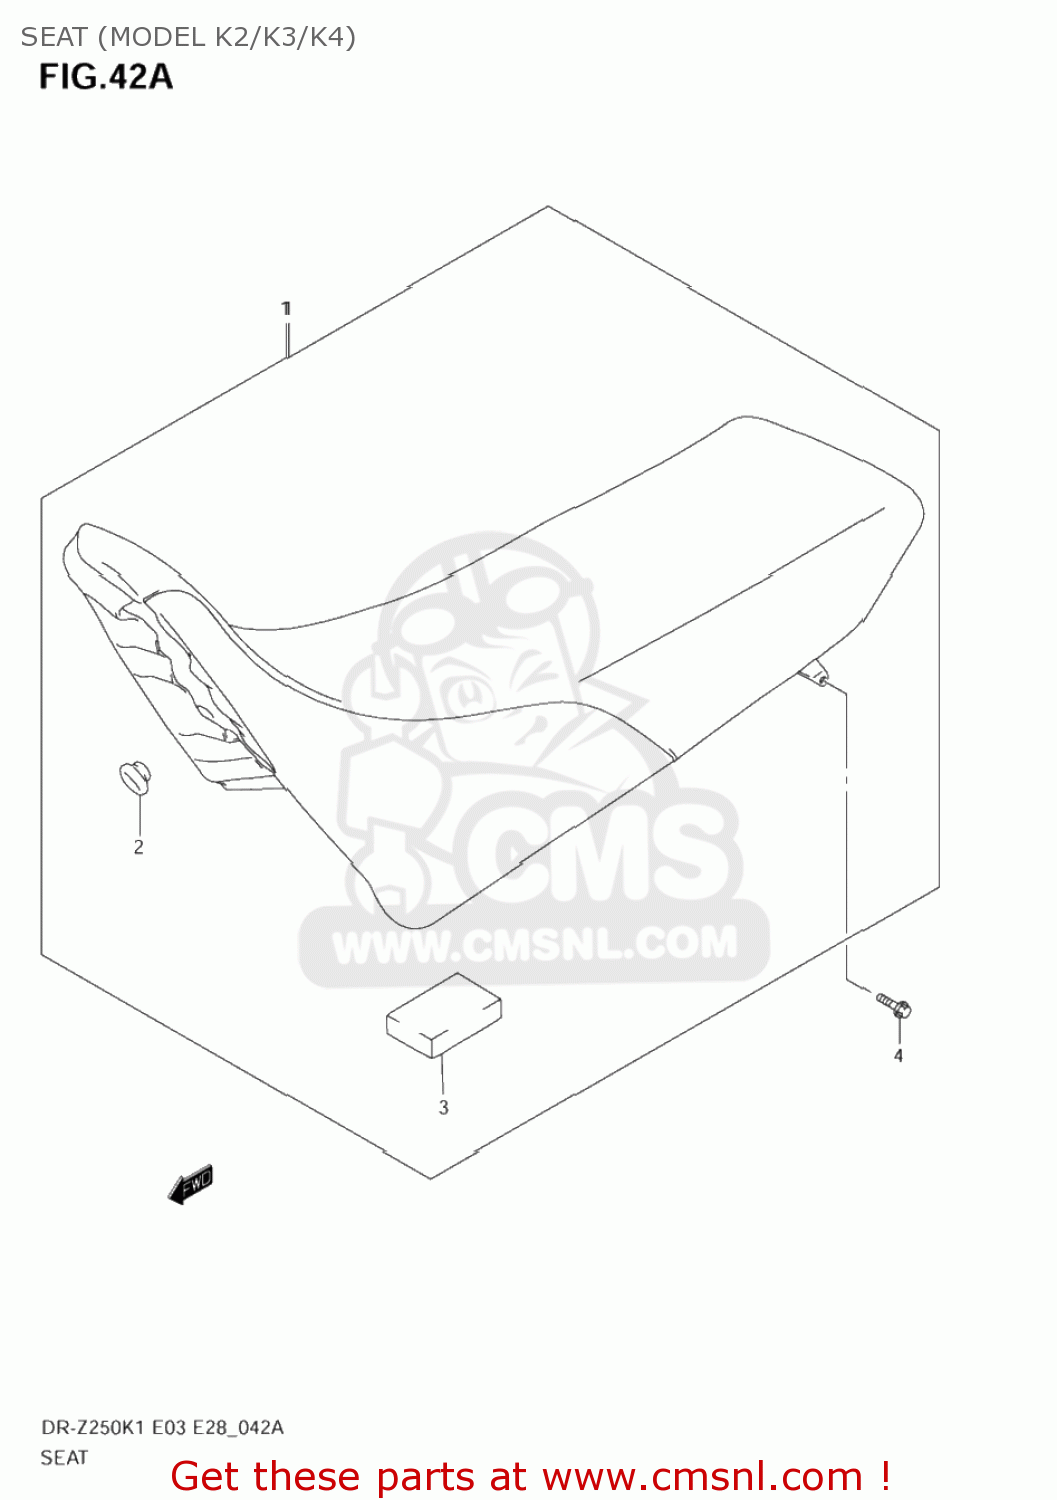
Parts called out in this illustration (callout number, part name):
1	SEAT ASSY
2	CUSHION
3	CUSHION
4	BOLT
